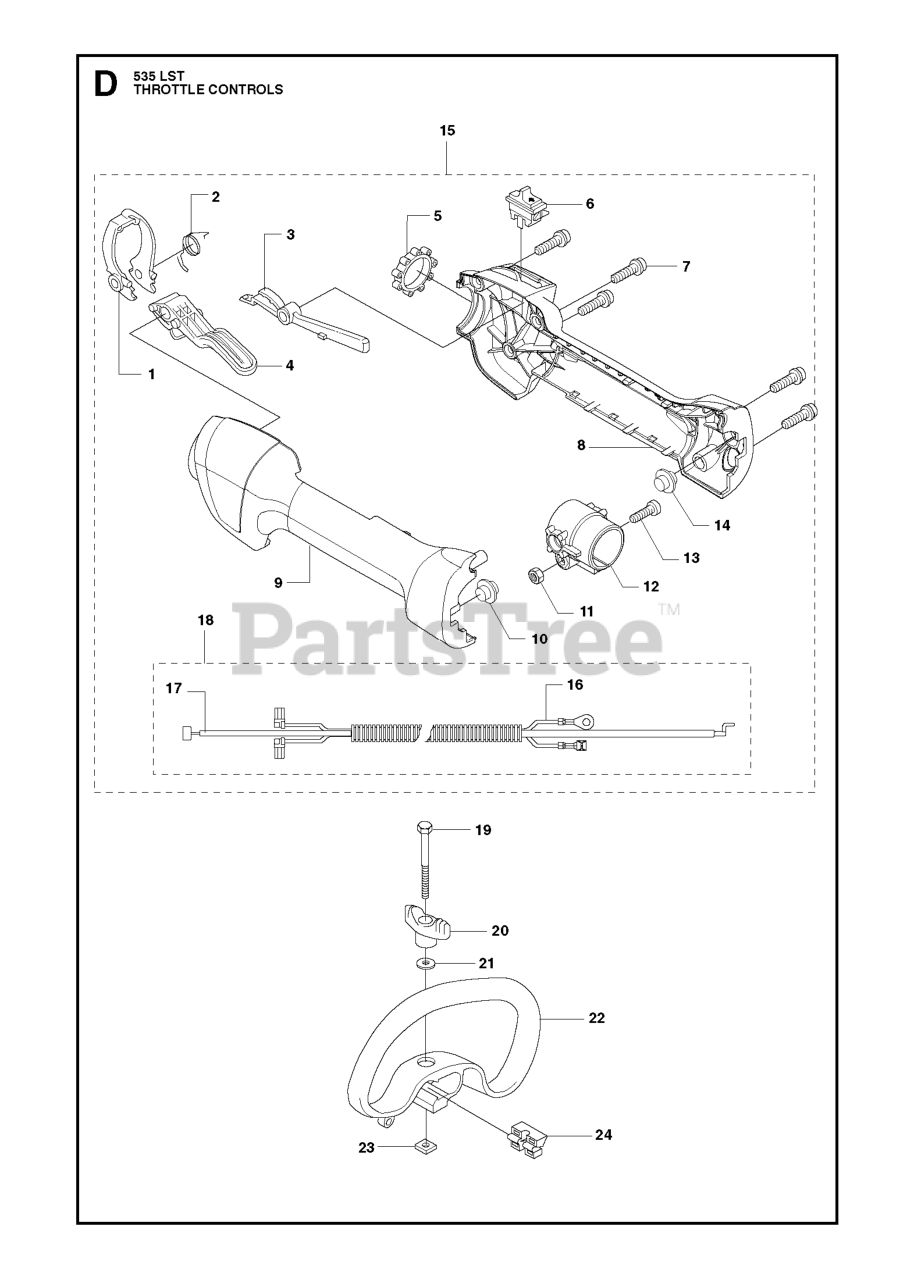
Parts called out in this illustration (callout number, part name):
2	RETURN SPRING
3	THROTTLE LOCK
4	THROTTLE TRIGGER
5	VIBRATION DAMPER
6	STOP BUTTON
8	HANDLE
9	HANDLE
15	CONTROL CPL R18 S-VERSION
16	SHORT CIRCUIT CABLE
17	THROTTLE WIRE ASSY
18	WIRING ASSY.
19	SCREW M6X50
24	SPACER PLASTIC
